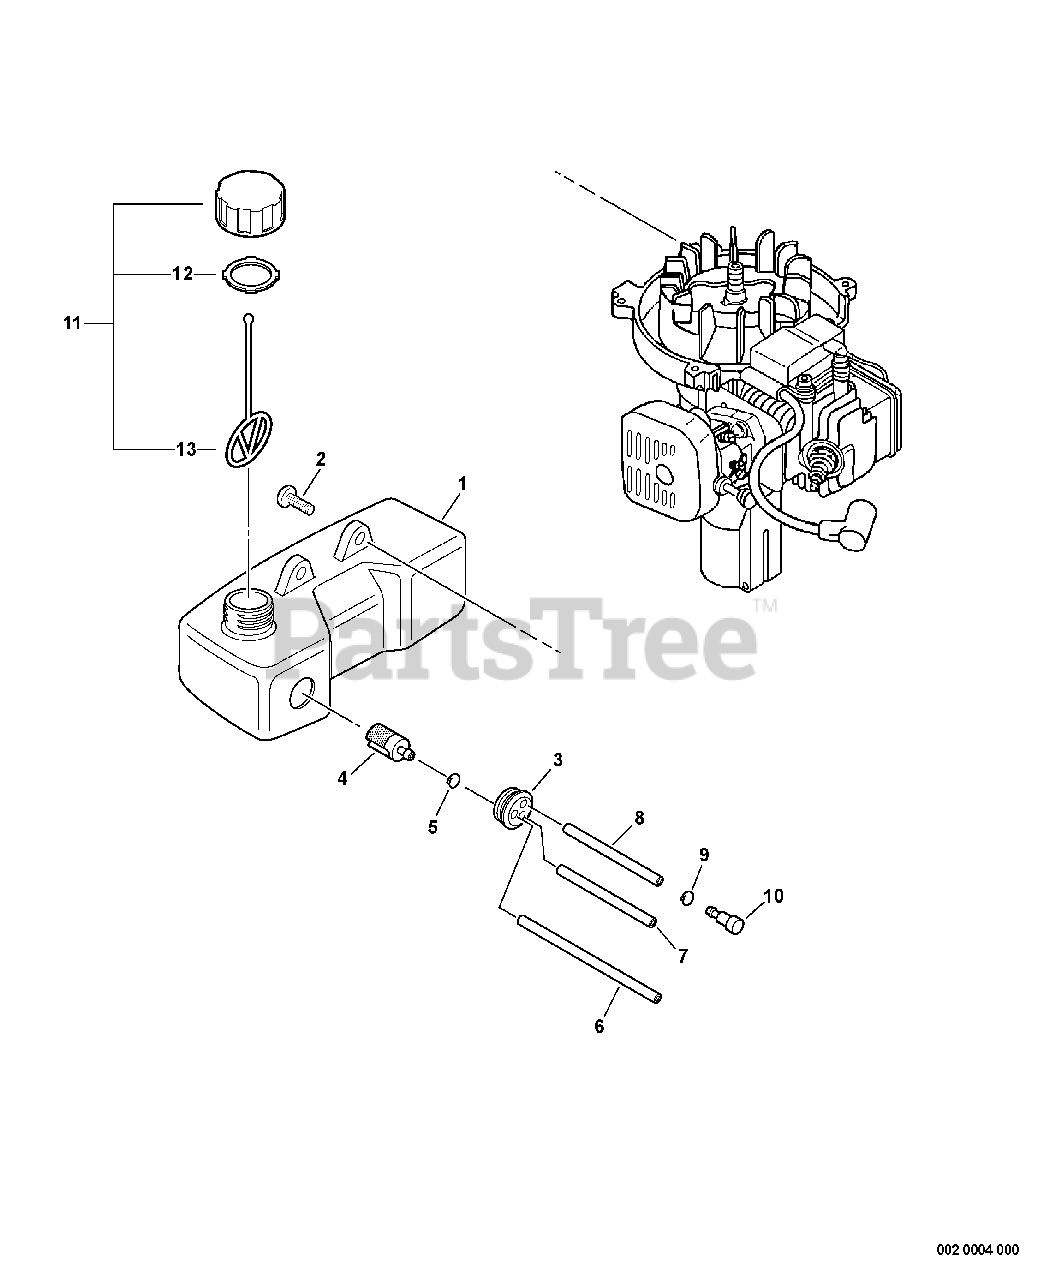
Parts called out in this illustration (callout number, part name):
1	TANK ASSY, FUEL
2	SCREW 5×15
3	GROMMET, FUEL
4	FILTER, FUEL
5	CLIP 6 MM
6	PIPE, FUEL 3×5×210 BLACK
7	PIPE, FUEL 3×6×50
8	PIPE, FUEL 3x-5x-70 BLACK
10	VENT ASSY
11	CAP ASSY
12	GASKET, FUEL CAP
13	CONNECTOR, CAP L= 100 MM
